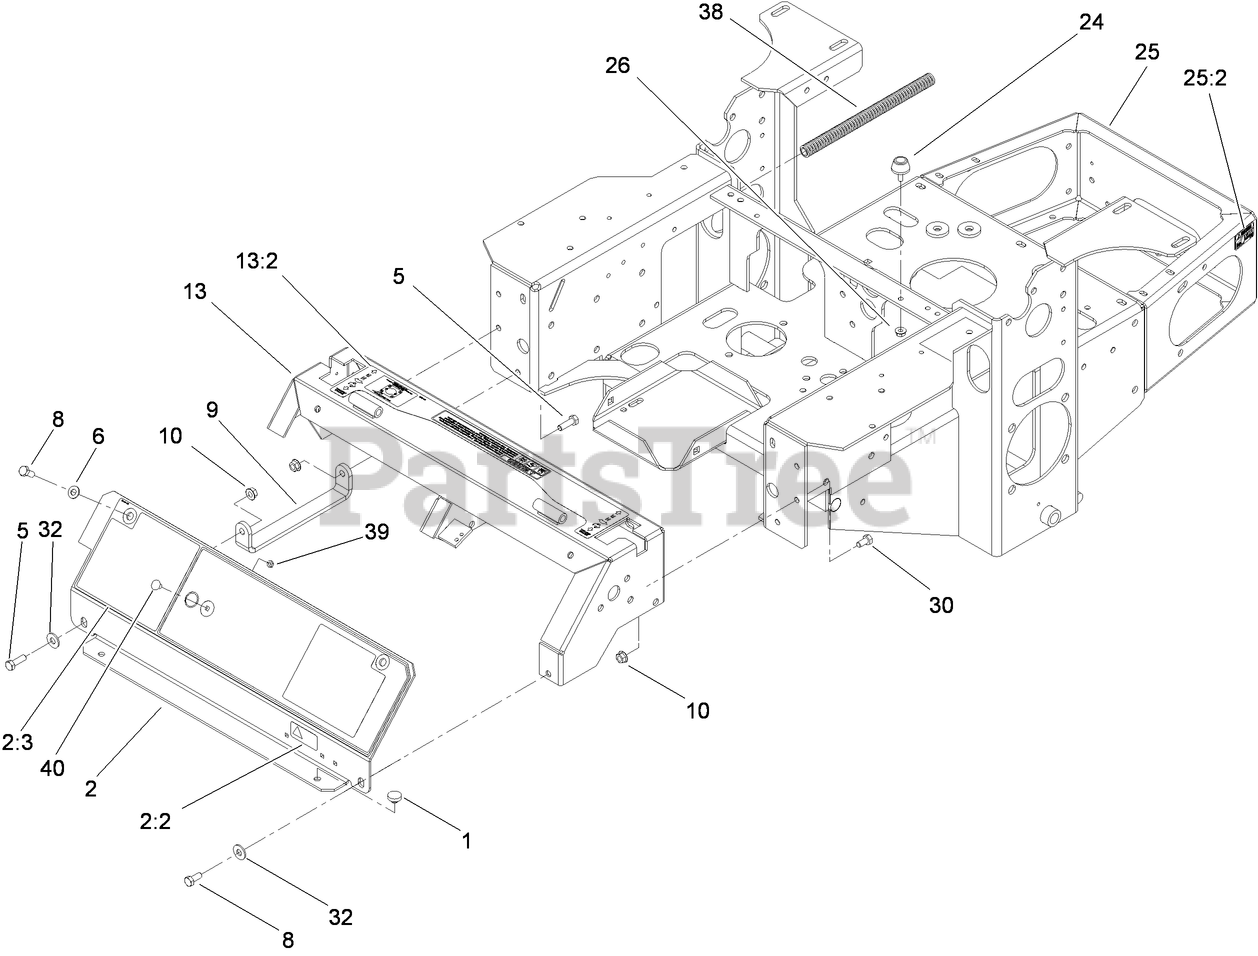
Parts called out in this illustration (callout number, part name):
1	BUMPER
2	PANEL ASM
2:2	DECAL-PROTECTION, EAR
2:3	DECAL-COVER, PANEL
5	SCREW-HH
6	WASHER-PLAIN
8	SCREW-HH
9	BRACKET-PANEL, INSTRUMENT
10	NUT-HF
13	CONSOLE ASM
13:2	DECAL-WARNING
24	BUMPER-RUBBER
25	MAIN FRAME ASM
25:2	DECAL-SURFACE, HOT
26	NUT-HF
30	SCREW-HH
32	WASHER-FLAT
38	CONDUIT-CONVOLUTED, SPLIT
39	NUT-LOCK, NI
40	BOLT-CARR
